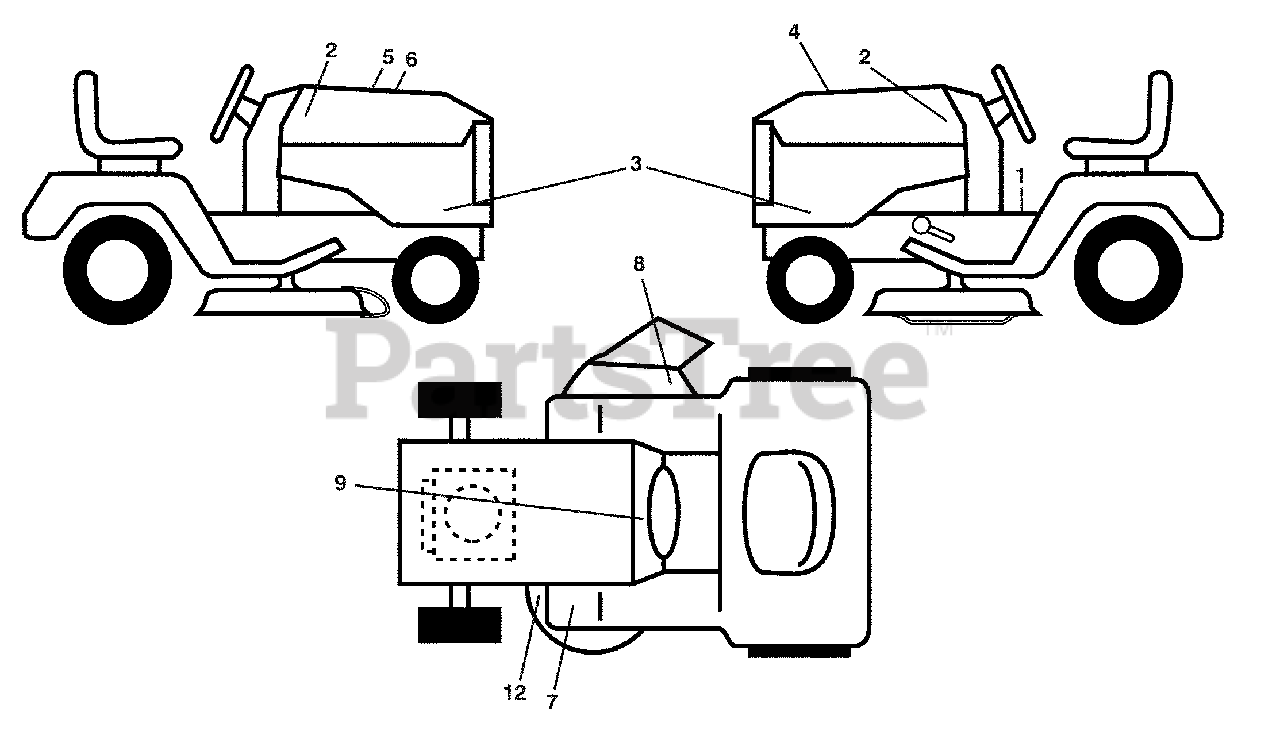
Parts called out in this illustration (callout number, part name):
1	Decal, Operators
2	Decal, Hood
3	Decal, Emblem Panel SD
4	Decal, Engine
5	Decal, Customer Respons.
6	Decal, Replacement
7	Decal, Pedal Husq. Crown
8	Decal Mower Warn Keep Hand away
9	Decal, Battery Dnge/Poi
12	Decal, Mower V-Belt Schematic
